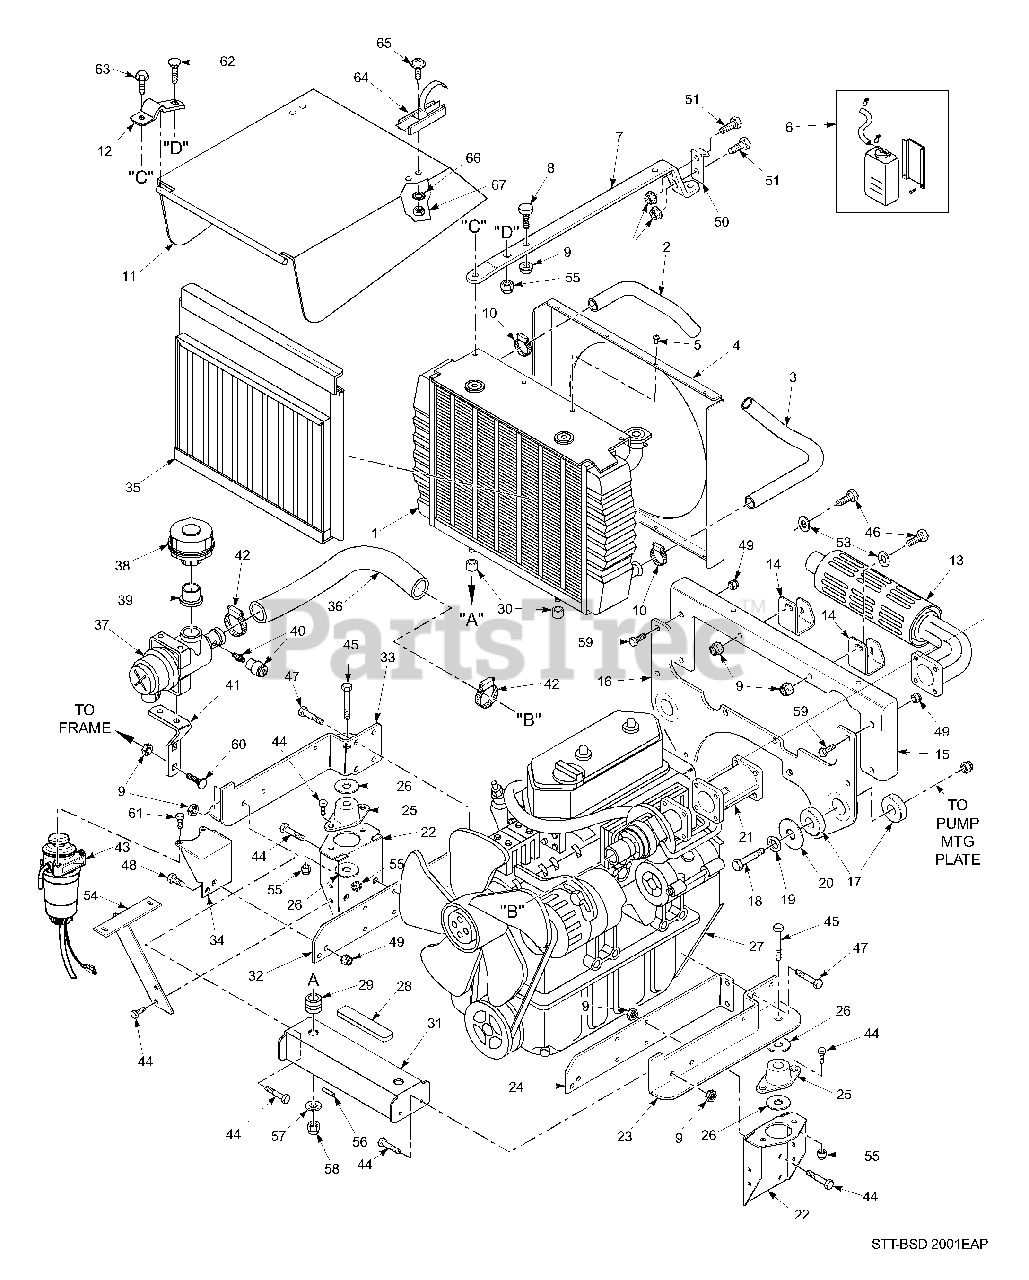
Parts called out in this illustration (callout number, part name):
1	Radiator
2	Hose, Upper Radiator
3	Hose, Lower Radiator
4	Shroud, Fan
5	Rivet, 3/16 x .402 Pop
6	Coolant Tank Assembly w/hose
7	Support Bracket, Hood
8	Bumper, Rubber
9	Nut, Serrated Flange 5/16-18
10	Clamp, 1-1/2" Dia.
11	Hood Weldment
12	Hinge, Hood
13	Muffler with Guard
14	Mounting Bracket, Muffler
15	Mounting Bracket, Hood
16	Mounting Bracket Weldment, Rear Engine Mount
17	Engine ISO Mount, Rear
18	Bolt, Hex Head 1/2-13 x 3-1/2"
19	Lockwasher, 1/2" Spring
20	Flatwasher, 1/2-.531 x 2.0 x .25
21	Manifold Extension, Exhaust
22	Mounting Bracket, Engine
23	Mounting Bracket Weldment, Engine L.H.
24	Mounting Bracket, Engine L.H.
25	Engine ISO Mount, Front
26	Flatwasher, 1/2-.531 x .062 x .095
27	Engine, Briggs & Stratton 31hp Diesel (Spec. #)
28	ISO Pad, Radiator
29	ISO Mount, Radiator
30	Bushing, Radiator ISO Mount
31	Support Bracket, Radiator
32	Mounting Bracket, Engine R.H.
33	Mounting Bracket Weldment, Engine R.H.
34	Mounting Bracket, Water Seperator
35	Shroud, Fan
36	Hose, Air Intake
37	Air Cleaner Assembly w/mounting Band
38	Pre Cleaner, Engine Air
39	Adapter, Pre Cleaner
40	Indicator, Air Cleaner
41	Bracket, Air Cleaner
42	Clamp, Hose 2-1/4" Dia.
43	Fuel Filter, Water Seperator
44	Bolt, Hex Head 5/16-18 x 3/4"
45	Bolt, Hex Head 1/2-13 x 2-1/2"
46	Bolt, Hex Head 5/16-18 x 1"
47	Bolt, Hex Head M8-1.25 x 3mm
48	Bolt, Hex Head 3/8-16 x 1-1/4"
49	Nut, Elastic Stop 3/8-16
50	Catch Bracket, Hood Latch
51	Bolt, Hex Head 1/4-20 x 3/4"
53	Flatwasher, 375 x .875 x .083
54	Mounting Bracket, Battery
55	Nut, Elastic Stop 5/16-18
56	Pin, Rue Cotter 1/2" Dia.
57	Flatwasher, 7/16-.469 x .922 x .065
58	Nut, Elastic Stop 7/16-14
59	Bolt, Hex Head 3/8-16 x 1"
60	Bolt, Carriage 5/16-18 x 3/4"
61	Bolt
62	Bolt, Carriage 5/16-18 x 1"
63	Bolt, Hex Head 5/16-18 x 3/4" Serr. Flange
64	Latch, Hood
65	Screw, #10-32 x .375
66	Lockwasher, #10 Spring
67	Nut, #10
